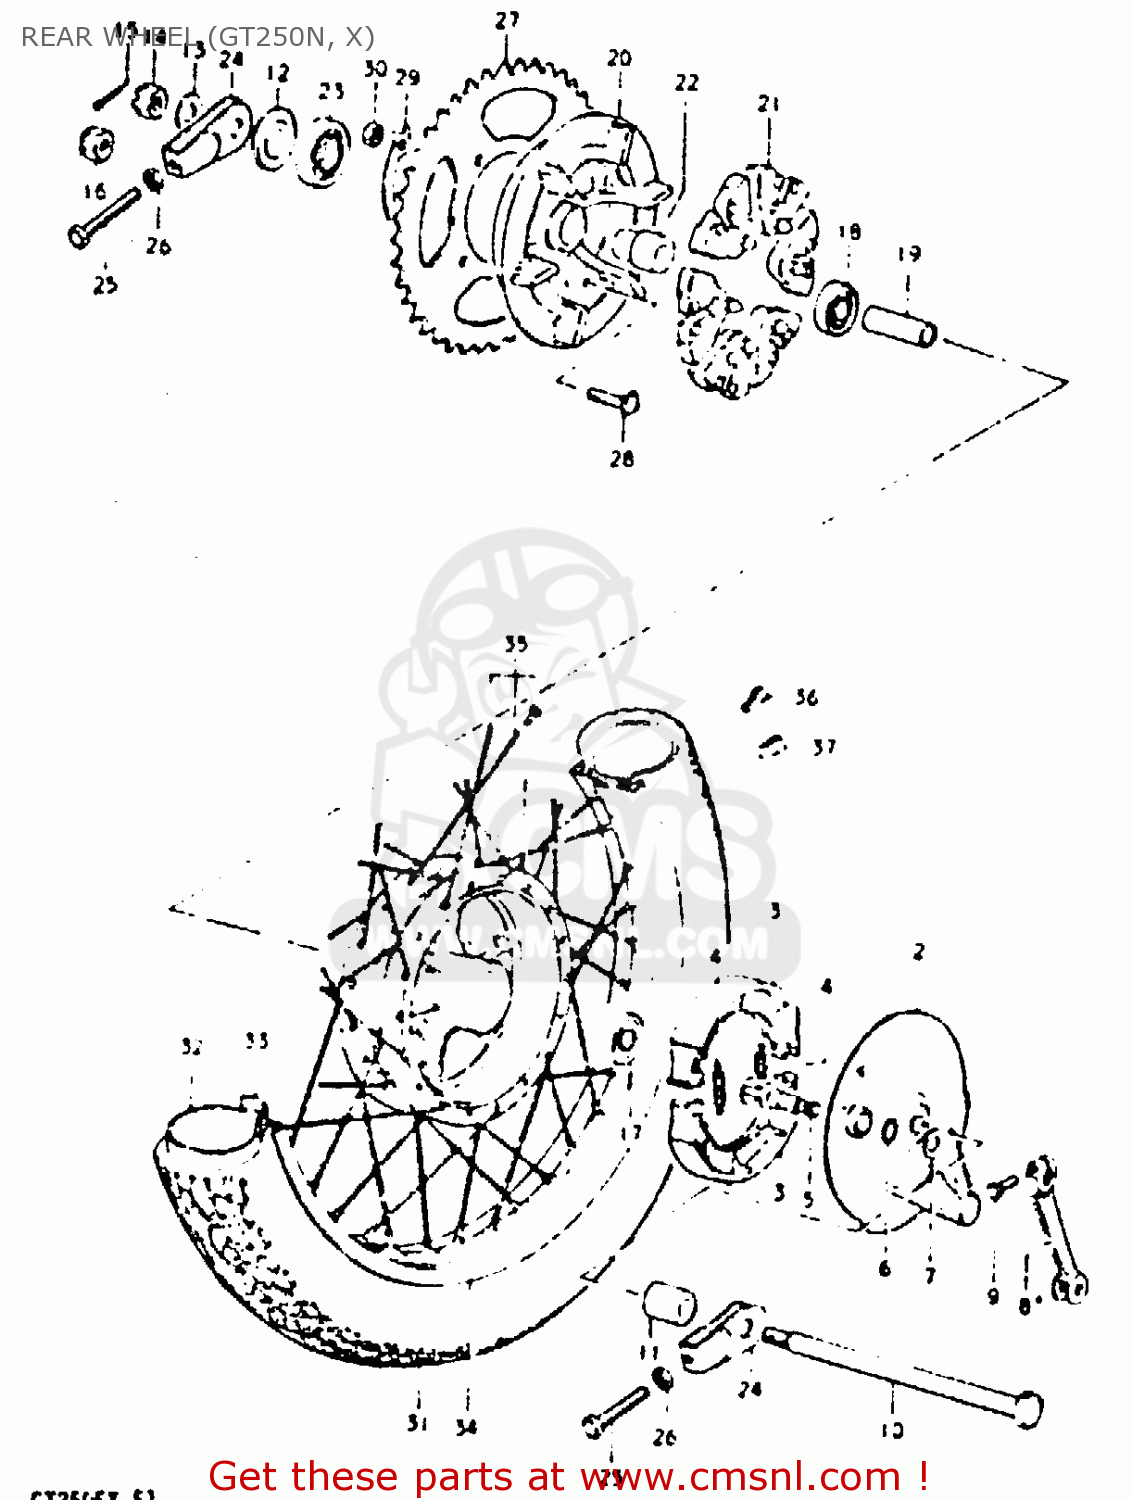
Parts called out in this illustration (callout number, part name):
1	HUB,RR
2	PANEL,REAR HUB
3	SHOE,BRAKE
4	SPRING,BRAKE SHOE
5	CAM,FRONT BRAKE
6	O-RING,BOSS
7	WASHER (15X24X1.6)
8	LEVER,RR BRAKE CAM
9	BOLT
10	AXLE, REAR
11	SPACER
12	SPACER, LH
13	WASHER
14	NUT
15	COTTER PIN
17	BEARING, RH
18	BEARING
19	SPACER(15.3X21.7X58)
20	DRUM,REAR SPROCKET MOUNT
21	ABSORBER,RR HUB SHOCK
22	RETAINER,RR SPROCKET MTG
23	BEARING
24	ADJUSTER,CHAIN,R
25	BOLT
26	NUT
27	SPROCKET,RR
28	BOLT(8X33.5)
29	WASHER,LOCK
30	NUT (8MM)
31	TIRE
32	TUBE ASSEMBLY,WHEEL,INNER
33	PROTECTOR,INNER TUBE
34	RIM,RR WHEEL
35	SPOKE SET
36	BALANCER,WHEEL (B)
37	BALANCER,WHEEL (30G)
